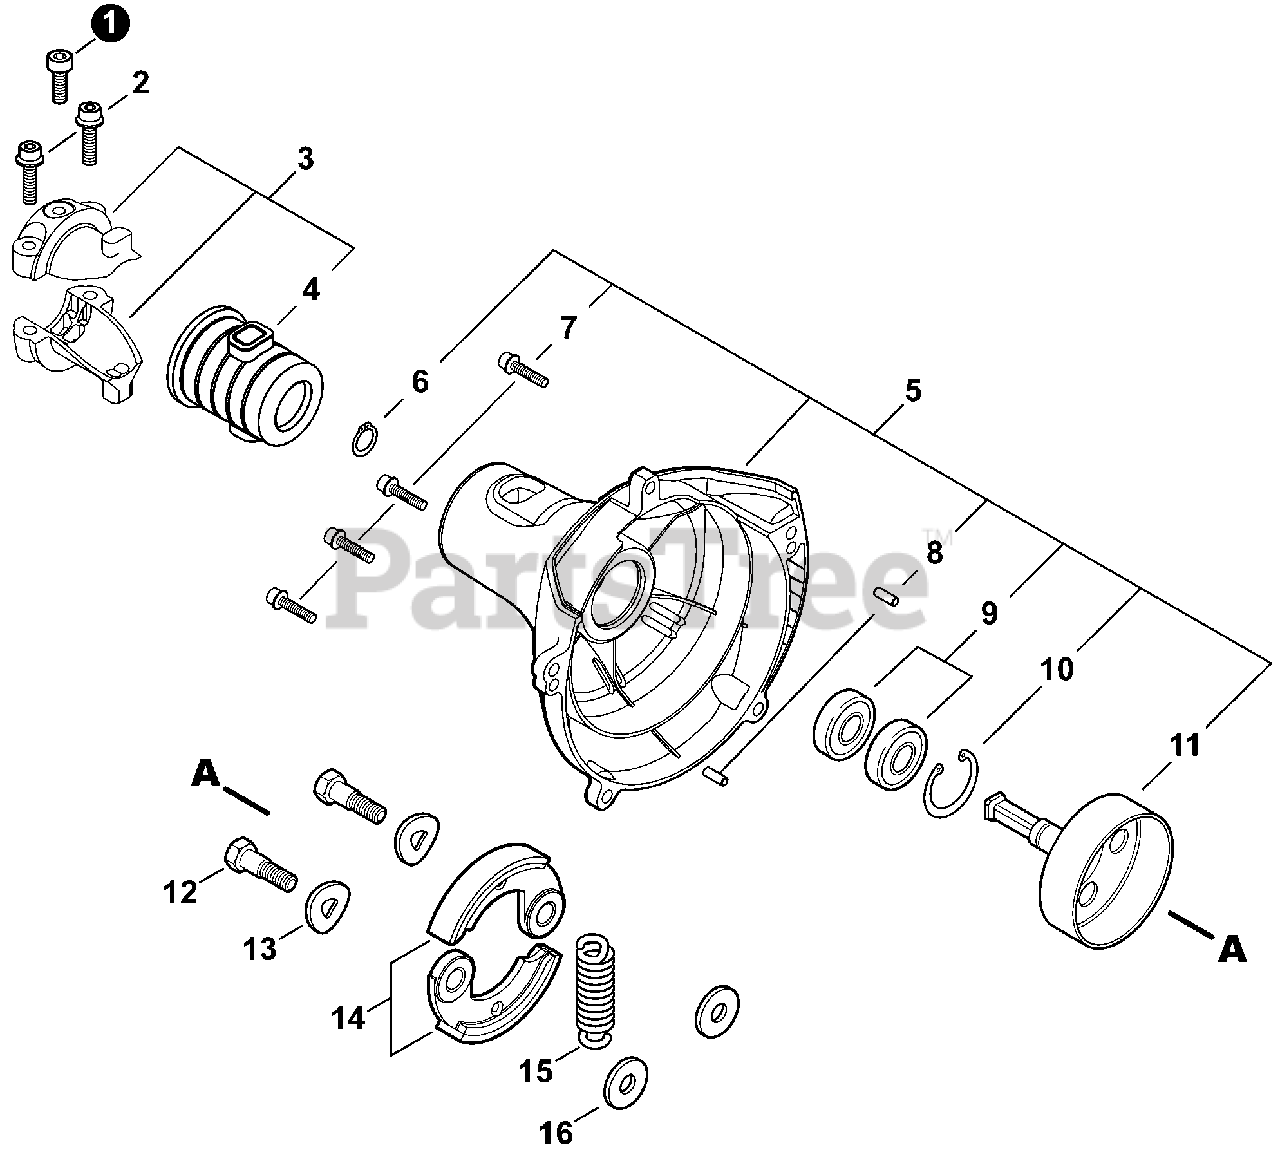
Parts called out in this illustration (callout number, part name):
1	SCREW 5×10
2	BOLT 5×25
3	FIXTURE KIT, MAIN PIPE
4	CUSHION
5	CASE ASSY, FAN
6	RING, RETAINING - 12
7	BOLT 5×20
8	PIN, LOCATING 4×8
9	BEARING, BALL 6001
10	RING, SNAP 28
11	DRUM, CLUTCH
12	BOLT, CLUTCH 8×7.9×M6
13	WASHER, SPRING 8.5×16×0.5
14	SHOE, CLUTCH
15	SPRING, CLUTCH
16	WASHER 6.2×19×1.0
